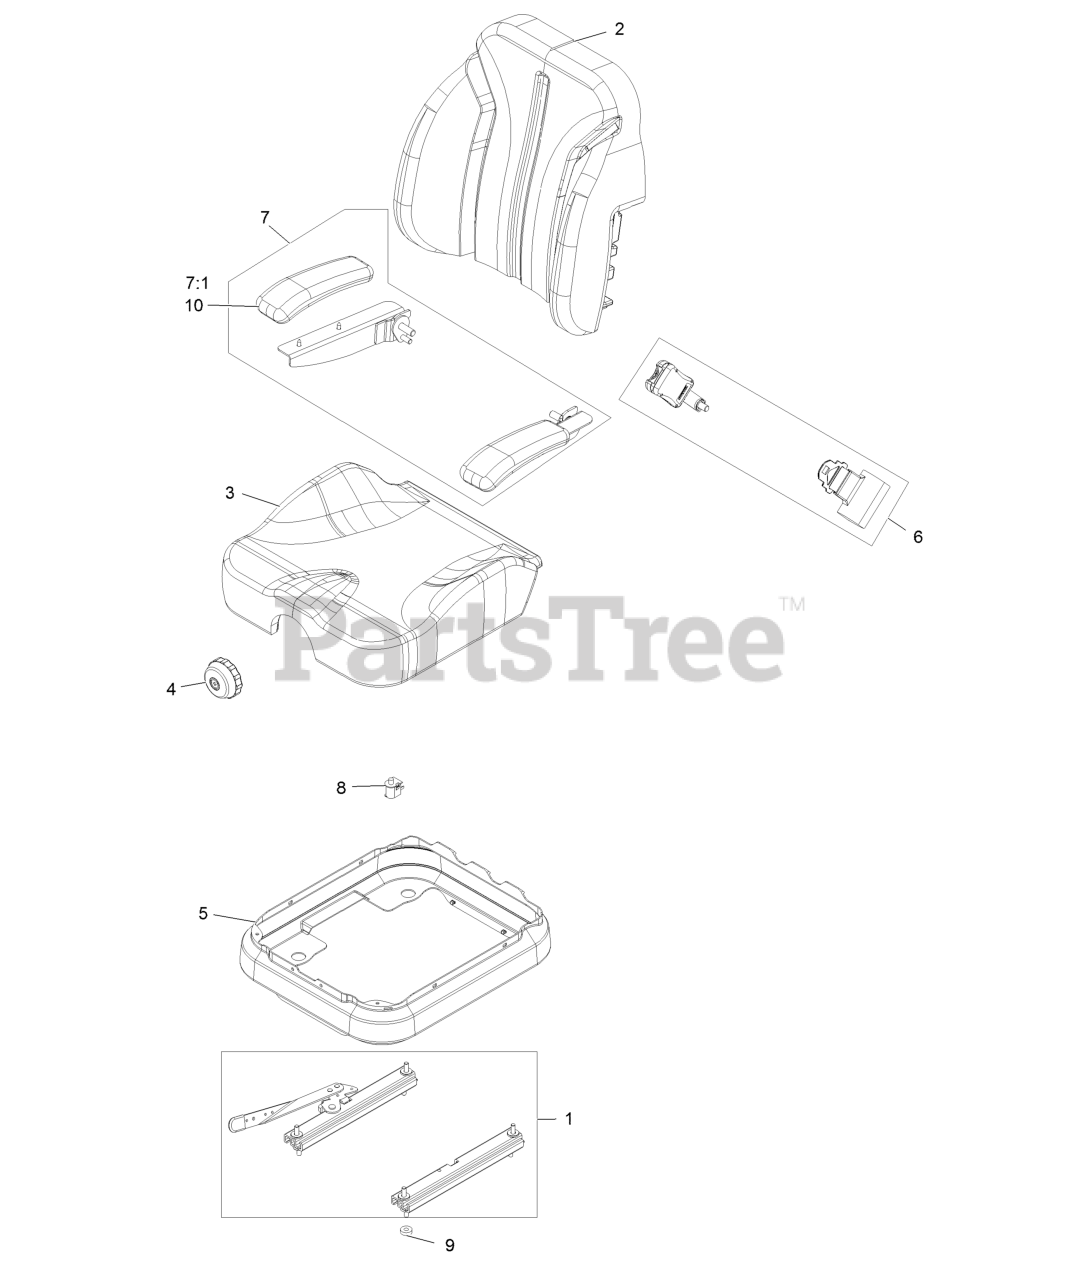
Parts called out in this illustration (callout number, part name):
1	Tracks-4" Travel
2	Cover-Seat Back Svc
3	Cover-Seat Bottom Svc
4	Knob-Adjuster
5	Bellows-Seat
6	Kit-Seat Belt
7	Armrest Kit
7:1	Cushion-Rest, Arm
9	Spacer-Pin, Mounting
10	Cushion-Rest, Arm
